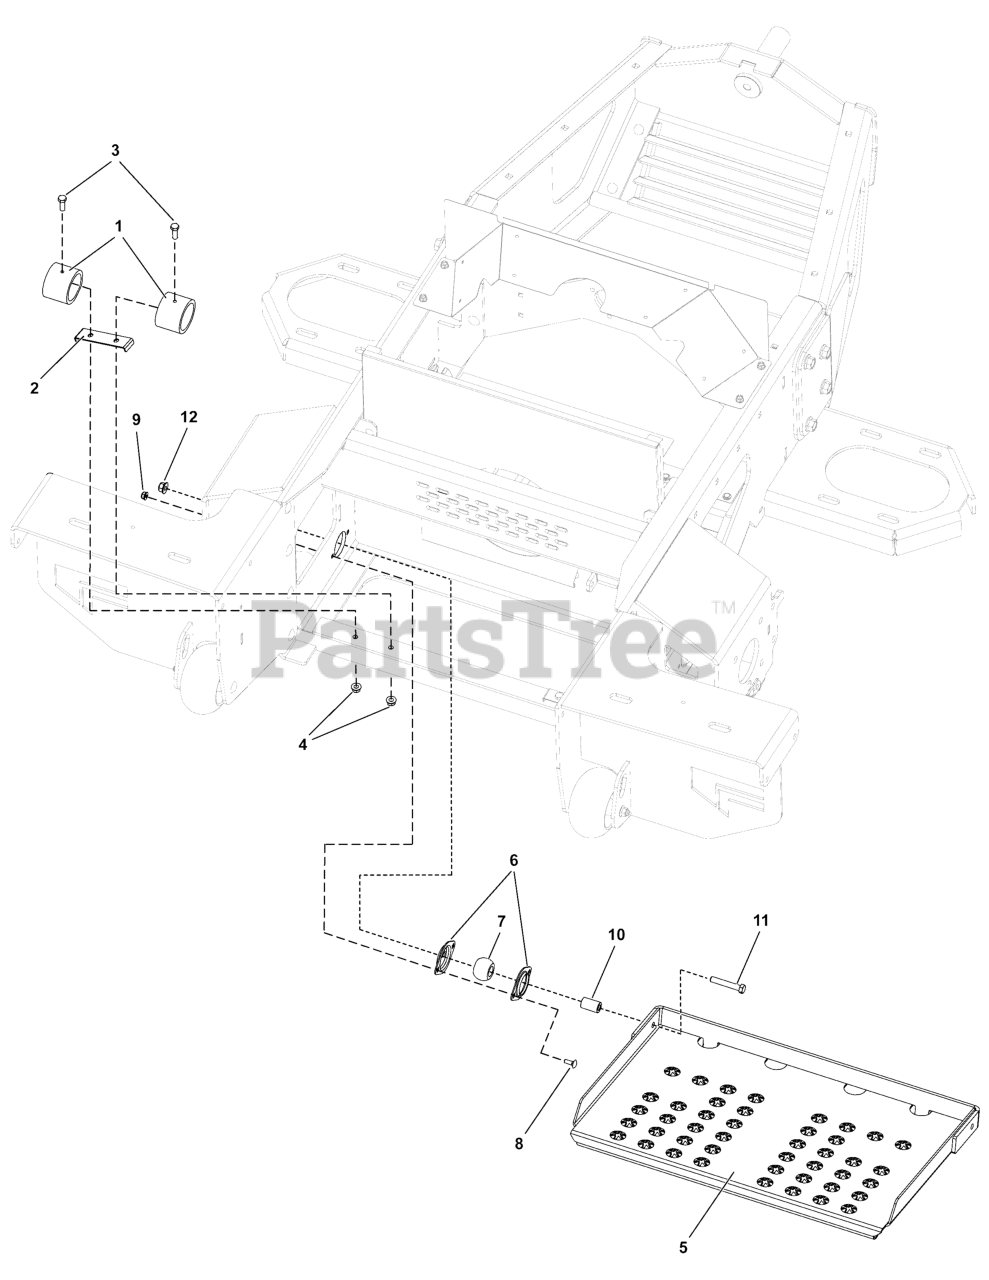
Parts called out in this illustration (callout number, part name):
1	BUMPER, GBR-6, 200 IN-LBS
2	BRACKET, GBR BUMPERS
3	SCR-CAP, HEX .3125"-18 X 1.250" SS188
4	NUT-HEX-NYLK, FLG .3125"-18 SS188
5	WELD, OPERATOR PLATFORM
6	40M-2-SS TWO-BOLT FLANGE
7	U40MMSPH-3/4 UHMW BEARING
8	BLT-RDHDSQNK .250"-20 X .750" SS188
9	NUT-HEX-NYLK, FLG .250"-20 SS188
10	SPCR-SS, 304 .375" X .750" X 1.250"
11	SCR-CAP, HEX .375"-16 X 2.250" SS188
12	NUT-HEX-NYLK, FLG .375"-16 SS188
